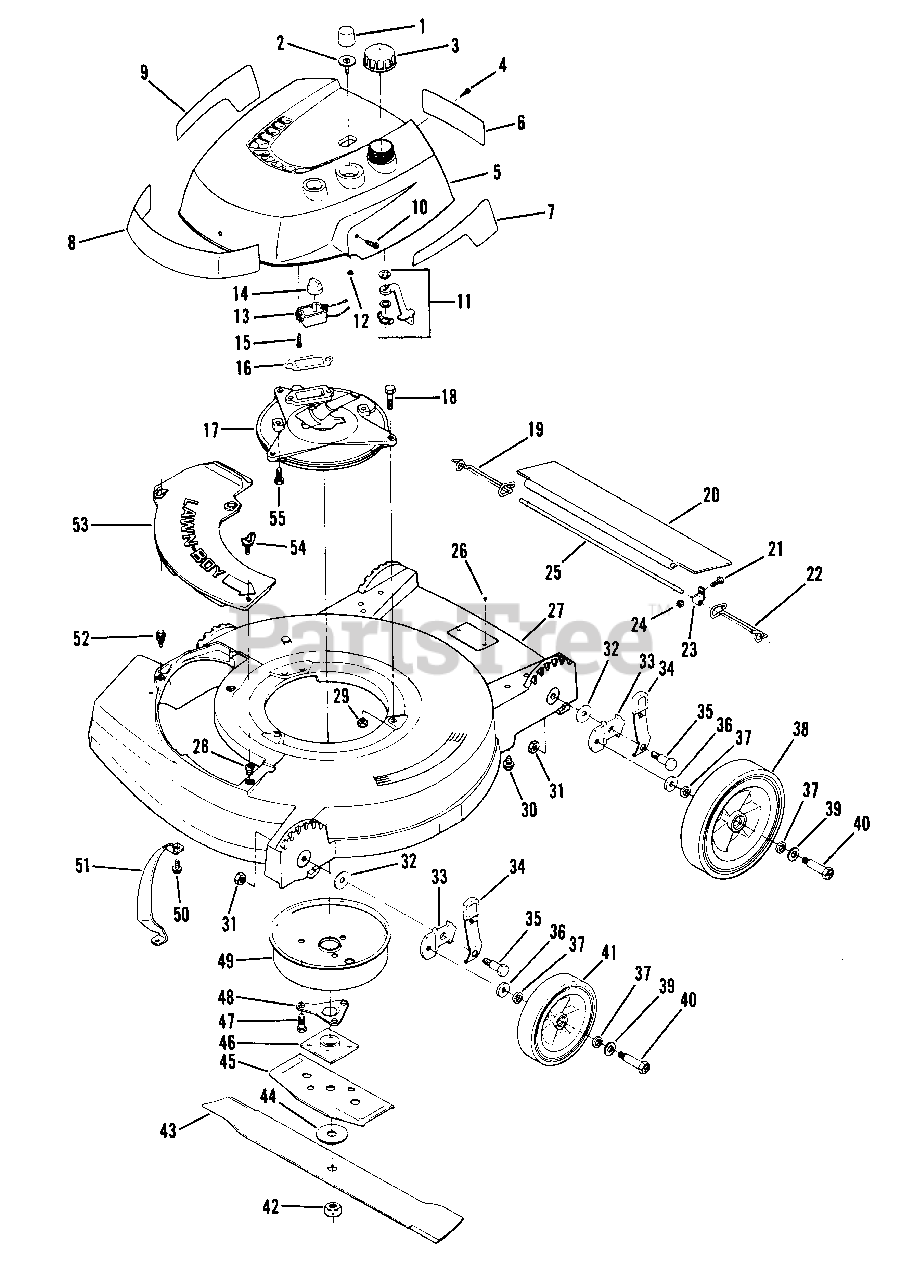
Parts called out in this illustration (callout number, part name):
1	Bulb-Primer
2	Base-Primer
3	Fuel Cap
4	Screw-Shroud to C.D. Bracket
5	Shroud-Engine
6	Decal-Instructions
7	Decal-L.H. 19"
7	Decal-L.H. 21"
8	Decal-Lawn-Boy
9	Decal-R.H. 19"
9	Decal-R.H. 21"
10	Screw-Shroud Mounting
11	Fuel Shut-Off Assembly
12	Nut
13	Switch-On-Off
14	Knob
15	Screw
16	Gasket-Exhaust
17	Plate-Muffler
18	Screw-Muffler Plate to Housing
19	Spring-R.H.
20	Shield-Trailing 19"
20	Shield-Trailing 21"
21	Screw
22	Spring-L.H.
23	Clamp
24	Nut
25	Rod-Trailing Shield 19"
25	Rod-Trailing Shield 21"
26	Screw-Model Plate Mounting
27	Housing-19"
27	Housing-21"
28	Grommet
29	Nut-Muffler Plate to Housing
30	Screw-Handle Bracket to Housing
31	Nut
32	Washer
33	Bracket-Wheel Height Adjustment
34	Knob & Spring Assembly
35	Shoulder Bolt
36	Washer
37	Washer-Felt
38	Wheel-Rear
39	Washer
40	Bolt-Wheel
41	Wheel-Front
42	Nut-Blade
43	Blade-19"
43	Blade-21"
44	Washer-Blade
45	Stiffener-Blade
46	Collar & Plate Assembly
47	Screw
48	Support-Crankshaft
49	Muffler Cover Assembly
50	Screw Sems
51	Toe Bar-19"
51	Toe Bar-21"
52	Screw-Sems-Plate & Chute Mounting
53	Cover Plate
54	Wing Screw
55	Screw-Muffler Plate to Block
